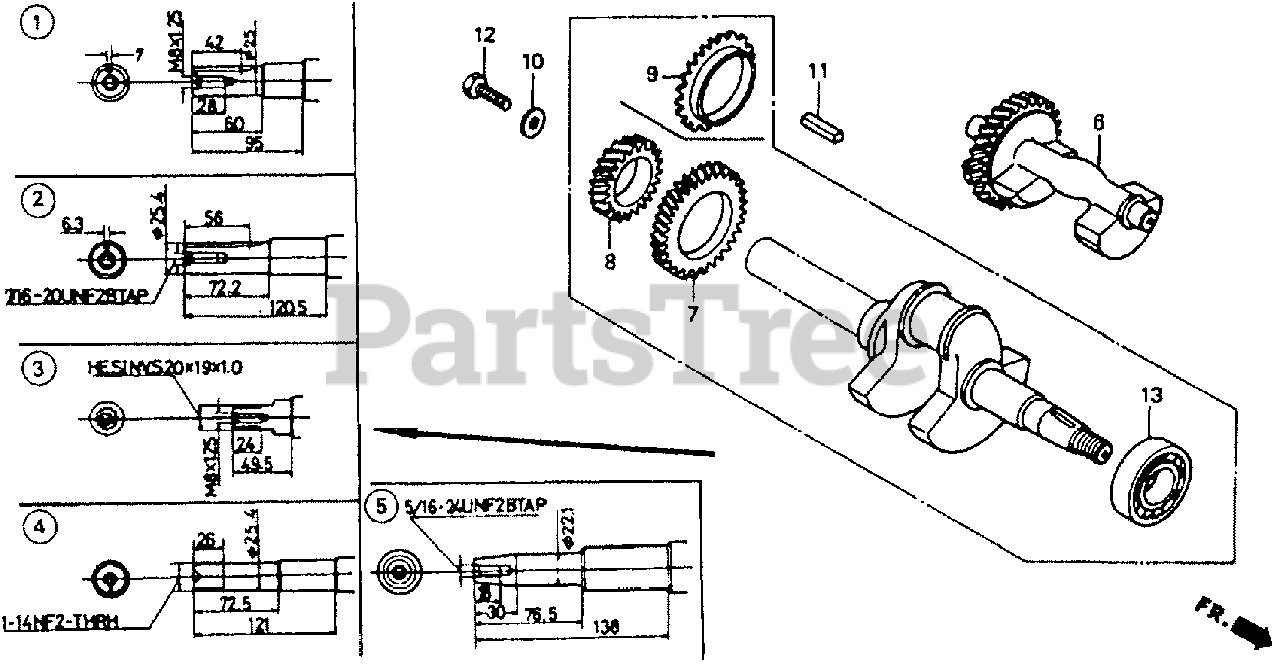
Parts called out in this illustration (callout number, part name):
5	CRANKSHAFT (V-TYPE)
6	WEIGHT, BALANCER
7	GEAR, BALANCER DRIVE
8	GEAR, TIMING
13	BEARING, RADIAL BALL (6206)
